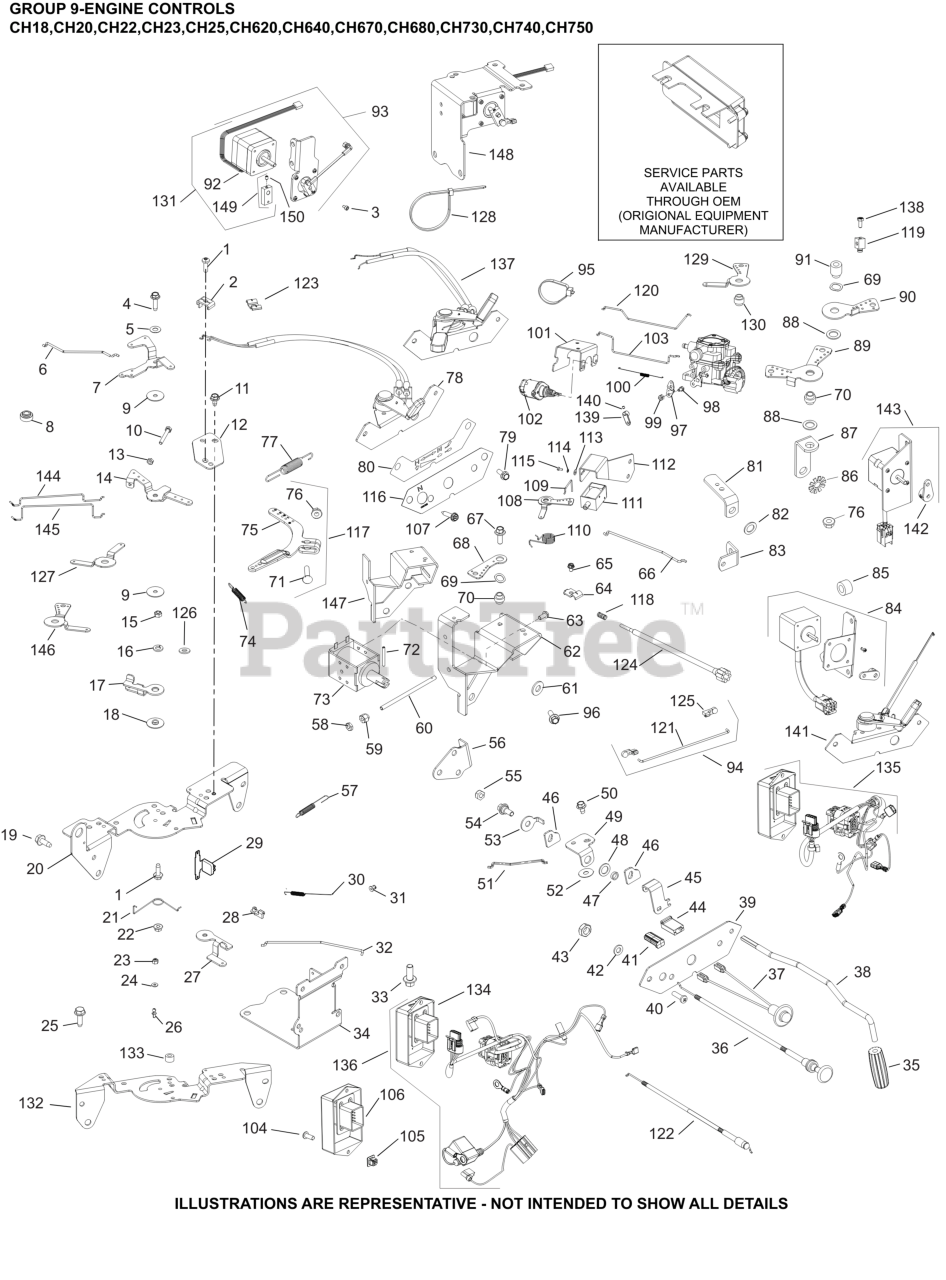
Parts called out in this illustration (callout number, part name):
1	SCREW, THREAD FORMING
2	CLAMP, CABLE CABLE
4	SCREW, THD FRM-USE 25 086 473-S
5	WASHER, SPRING 1/4"
7	LEVER, CHOKE
9	WASHER, FLAT 5.5 MM
10	SCREW, CAP M4X.7X30
13	NUT, M4X0.7
14	LEVER, THROTTLE CONTROL
15	NUT, FLG M5X.8
16	WASHER, SPRING LOCK 1/4"
19	SCREW, THREAD FORMING
20	BRACKET, CONTROL
21	SPRING, CHOKE RETURN
22	NUT, LOCK M5X.8
27	LEVER, THROTTLE ACTUATOR
28	BUSHING, THROTTLE LINKAGE
30	SPRING, LINKAGE
31	BUSHING, LINKAGE RETAINING
32	LINKAGE, THROTTLE
57	SPRING, THROTTLE LIMITER
71	BOLT, RD HD SQ NECK M6X1.0X25
75	LEVER, GOVERNOR - (#2409069S)
76	NUT, FLG M6X1.0
77	SPRING, GOVERNOR (PURPLE)
79	SCREW, HI-LOW
95	TIE, CABLE
117	LEVER, GOVERNOR ASSEMBLY
119	CLAMP, CABLE
138	SCREW, HEX MACHINE HEAD
144	LINKAGE, CHOKE
